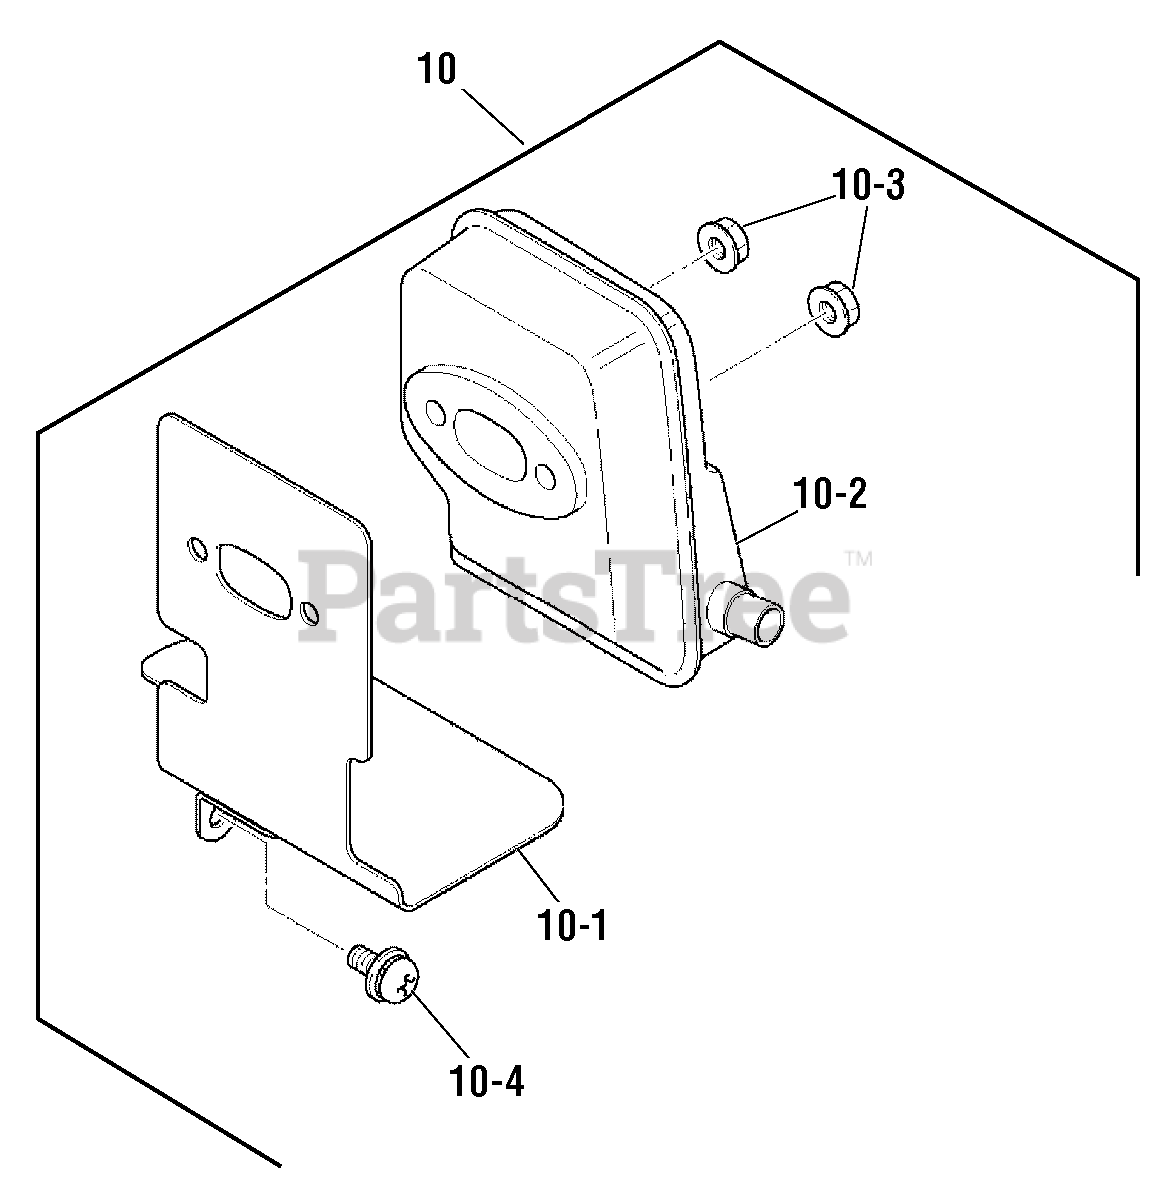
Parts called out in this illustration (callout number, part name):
10	MUFFLER & GASKET KIT
10-1	GASKET, Muffler
10-2	MUFFLER
10-3	NUT, Flange
10-4	SCREW & WASHER
